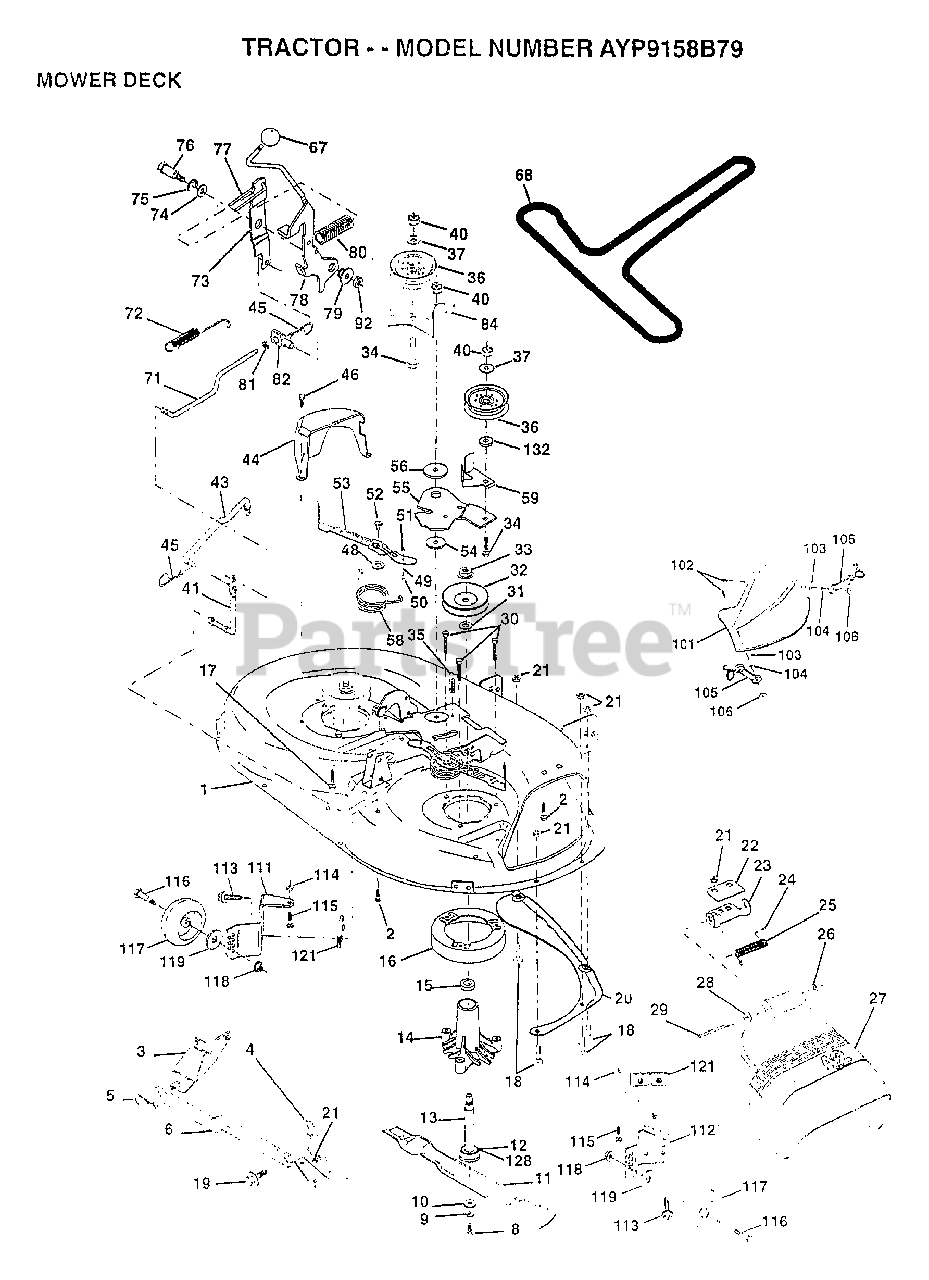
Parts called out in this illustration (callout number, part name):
1	DECK.WELD.42.
2	BOLT
3	BRKT ASM SWAY BAR
4	BRKT DECK SW BAR
8	BLADE BOLT
10	WASHER.HARD.BLADE
11	"BLADE.42"" MULCHER"
12	BEARING.BALL
14	HSG ASM MANDREL
15	BEARING
16	STRIPPER RND MWR
17	BOLT RDHD 3/8-16
18	BOLT
19	BOLT SHD 5/16-18
22	STIFFENER BRKT
23	DEFLECTOR BRKT
24	CAP-SLEEVE LT
25	SPRING TORSION
26	NUT PUSH M
27	DEFLECTOR.SHIELD
28	WASHER
29	HINGE ROD
31	WASHER
32	PULLEY.MANDREL.42
34	BOLT
35	XMAS TREE FASTNER
36	FLAT IDLER PULLEY
37	WASHER
41	PIVOT ROD
43	ROD CLUTCH W/NIBS
44	GUARD MAND LH BLK
45	RETAINER M
46	SCREW.1/4-20X5/8
48	HARD SMALL WASHER
49	ROLLER ASM-CAM
50	SHOULDER BOLT
51	LOCKNUT
52	BOLT.SHLD.5/16-18
54	HARDENED WASHER
55	ARM-IDLER
56	SPACER RETAINER
58	SPRING TORSN BRAK
59	GUARD IDLER TUV
67	KNOB T(3/8 HOLE)
68	BELT-V.SEC.46.KEL
71	ROD CLUTCH 38/42
72	RETURN SPRING
73	CLUTCH ARM SECOND
74	WASHER
75	RING
76	SHOULDER BOLT
77	SPRING KEEPER
78	LEVER ASM-CLUTCH
79	BUSHING
80	SPRING.CLUTCH.MWR
82	TRUNION ADJ
84	BRACKET ASM IDLER
92	NUT
101	"COVER.MULCH.42"""
102	SCREW
103	WASHER #10
104	LOCKWASHER
106	WELDNUT
111	BRACKET.GWHL.LH.
112	BRACKET.GWHL.RH.
113	SCREW
116	BOLT.SHOULDER
117	WHEEL GAGE DONUT
118	LOCKNUT
119	WASHER
121	BRACKET.EXTRD.GWL
128	WASHER.FELT.
132	WASHER GT
